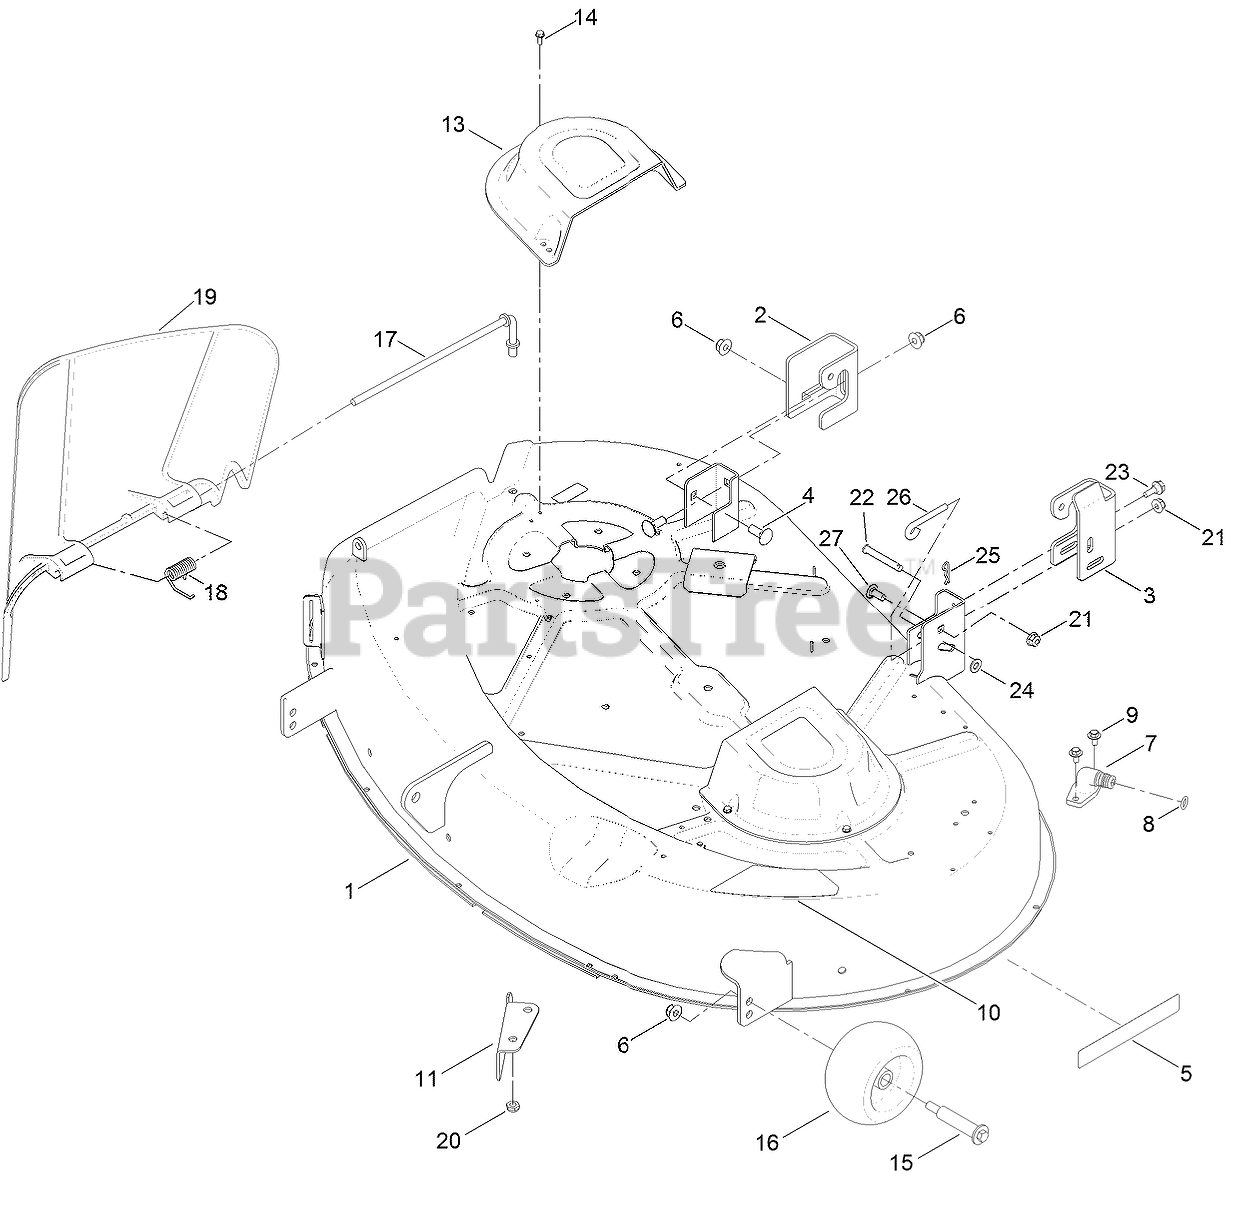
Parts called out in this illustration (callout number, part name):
1	42 INCH DECK AND DECAL ASM
2	BRACKET-HANGER, RH
3	BRACKET-HANGER, LH
4	BOLT-CARR
5	DECAL-RECYCLER
6	NUT-HF, NI
7	FITTING-WASHOUT
8	O-RING
9	SCREW-HHFTF
11	BAFFLE-CUTOFF
13	COVER-BELT
14	SCREW-TAPTITE
15	BOLT-SHOULDER
16	ROLLER-SCALP, ANTI
17	ROD-PIVOT
18	SPRING-TORSION
19	DEFLECTOR
20	NUT-LOCK, NI
21	NUT-HF, NI
22	PIN-CLEVIS
23	SCREW-SHOULDER, HHF
24	WASHER-PLAIN
25	PIN-COTTER
26	ROD-LEVEL, DECK
27	SCREW-CARR
